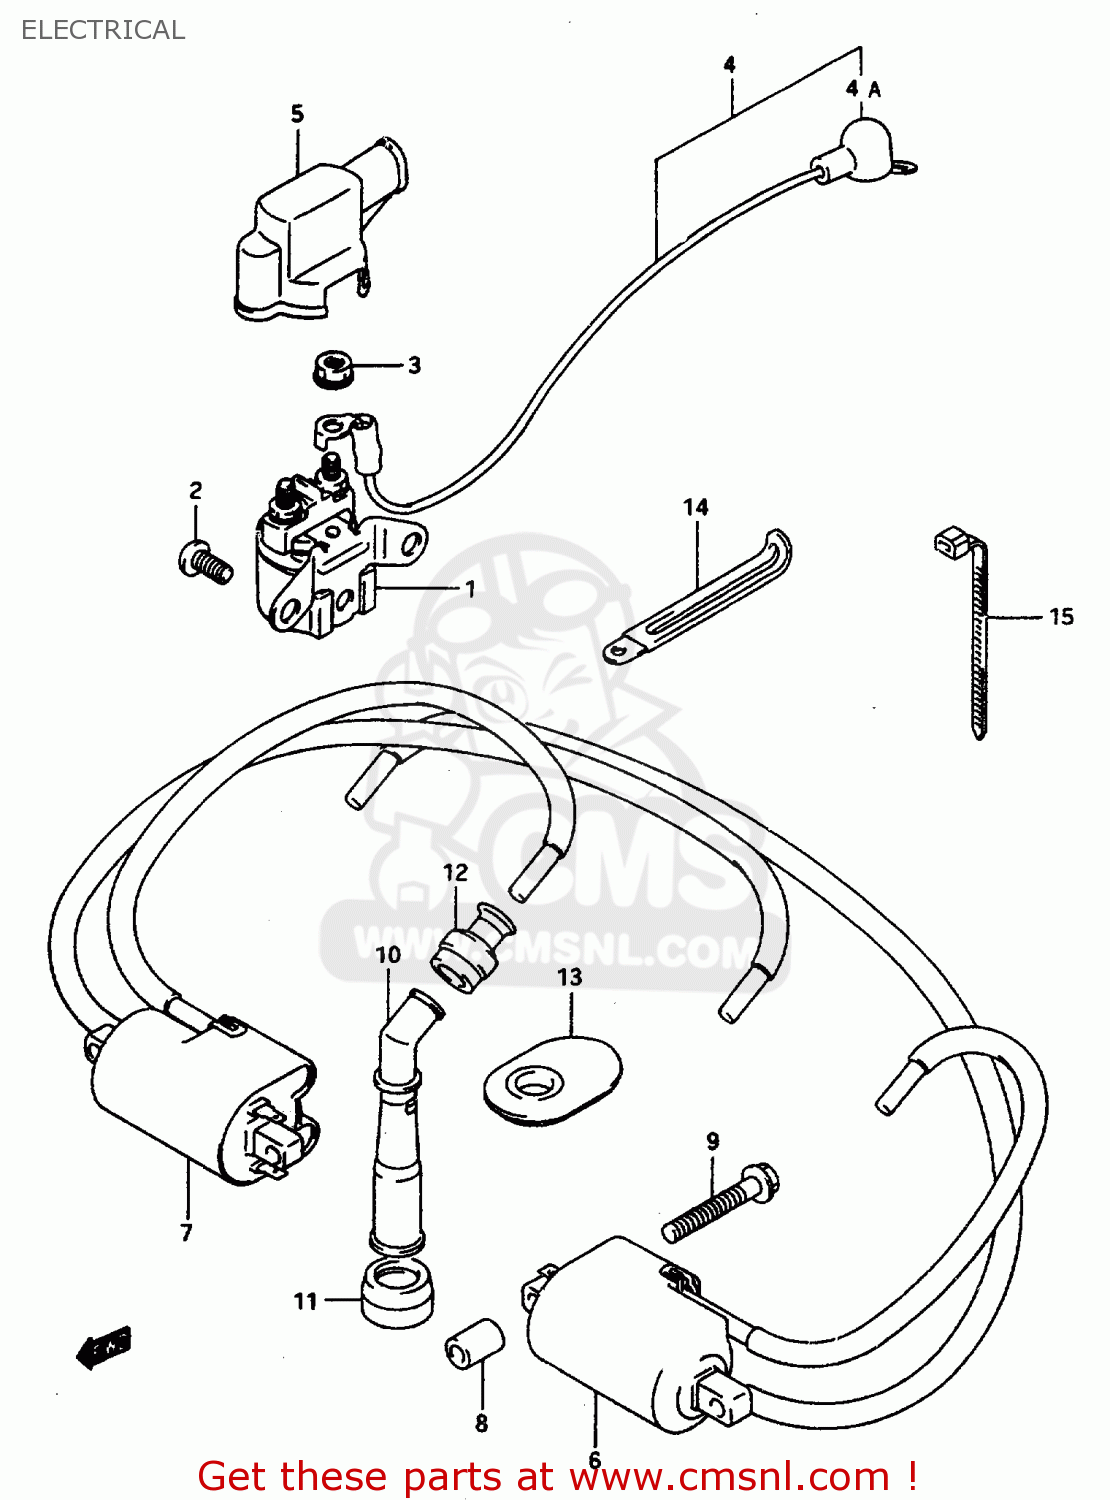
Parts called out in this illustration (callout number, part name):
1	RELAY ASSY,STARTING MOTOR
2	SCREW
3	NUT
4	WIRE,STARTER MOTOR LEAD
4A	CAP,STARTER MOTOR LEAD
5	CAP,STARTER RELAY
6	COIL ASSEMBLY,IGNITION NO
7	COIL ASSEMBLY,IGNITION NO
8	SPACER(6.2X12X16)
9	BOLT (6X45)
10	CAP,SPARK PLUG
11	SEAL,SPARK PLUG CAP
12	SEAL,HIGH TENSION CORD
13	COVER,SPARK PLUG CAP
14	CLAMP(L:65)
15	CLAMP L:165
